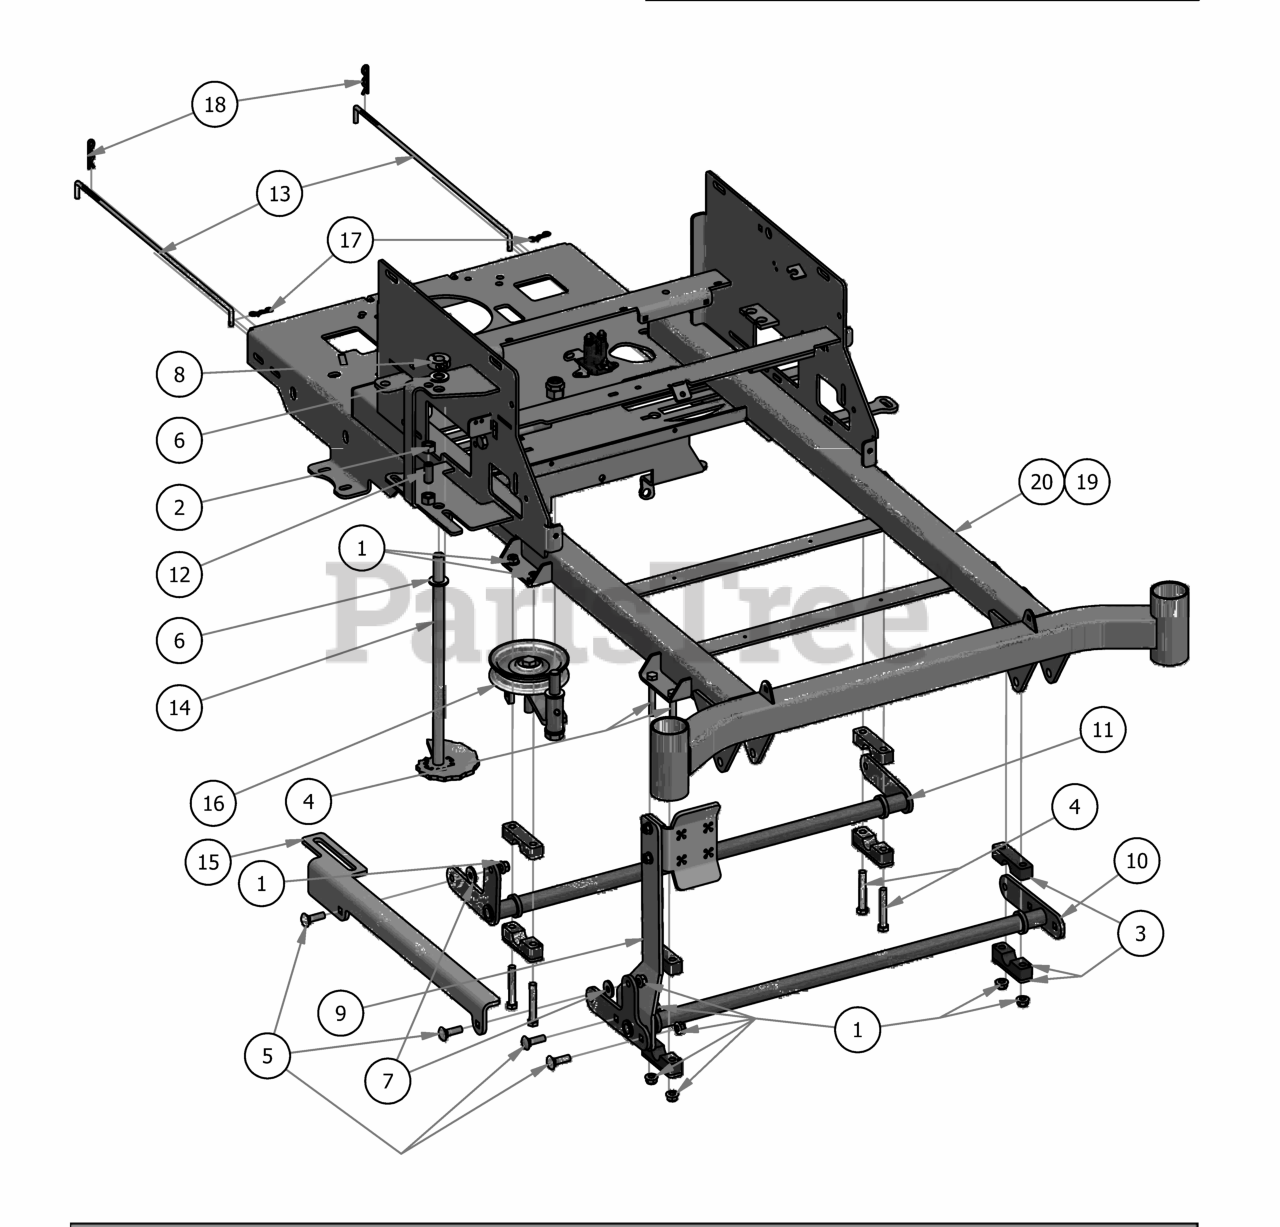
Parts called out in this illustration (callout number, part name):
1	3/8" Nylock Flange Nut
2	1/2" Hex Nut
3	Pillow Block Kit
4	3/8-16 x 2 1/2" Hex Bolt
5	3/8" x 1 1/4" Carriage Bolt
6	.630 ID x 1.122 OD x .142 THK Plastic Washer
7	.360 ID Plastic Washer
8	5/8" Split Collar
9	Foot Pedal Assembly
10	Actuator Bar Front- 2017 MZ/ZT
11	Actuator Bar Rear- 2017 MZ/ZT
12	Dial Rod Plunger
13	Neutral Rod
14	ZT Deck Height Bar Assembly
15	2017 MZ/ZT Actuator Linkage
16	ZT Pump Idler
18	Neutral Rod Clip
19	ZT 54" and 60" Frame
20	2017 MZ/ZT 42"-48" Frame
